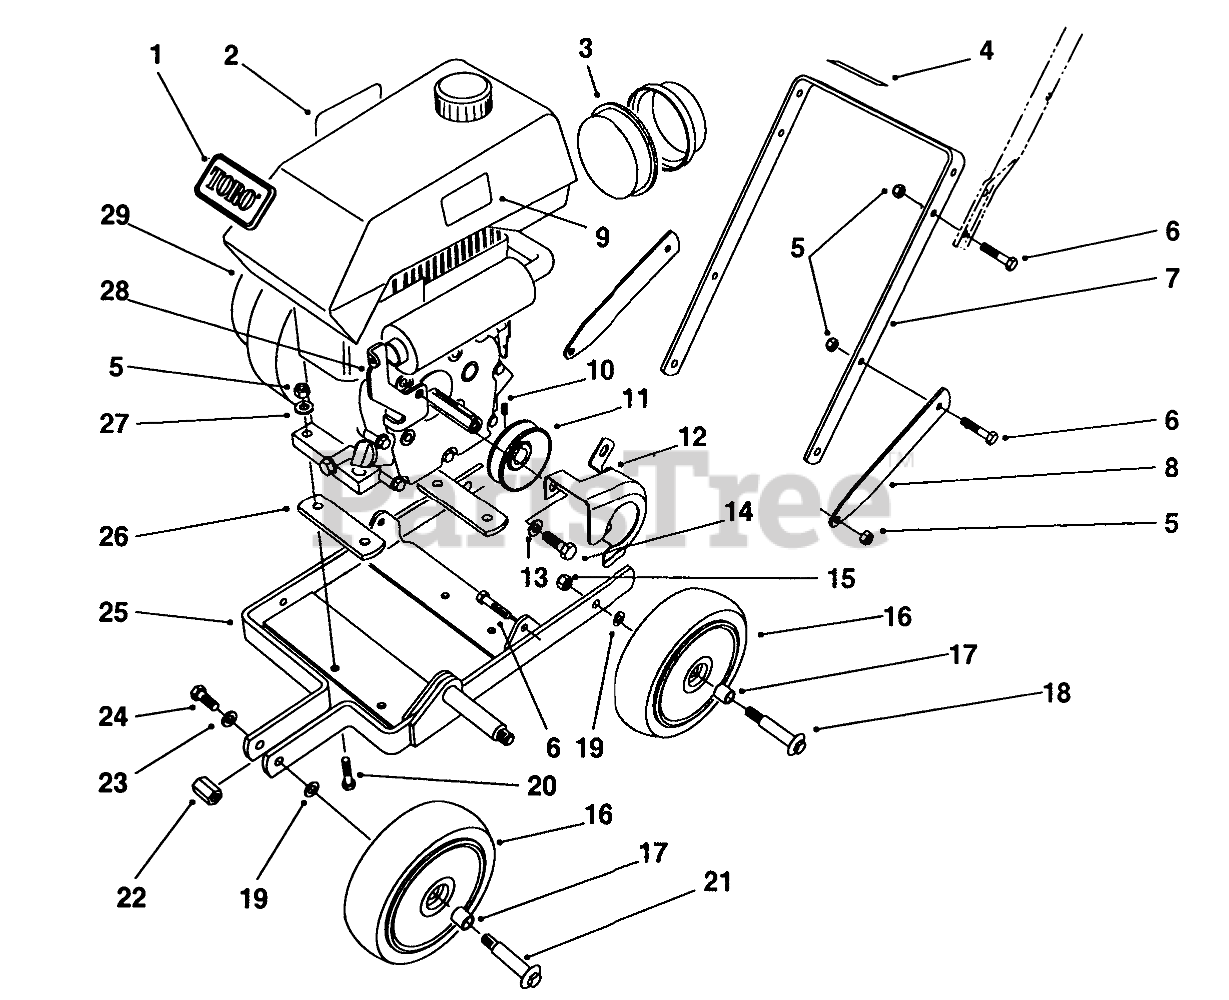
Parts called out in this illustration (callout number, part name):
1	TORO LOGO PLT
2	OPERATING INST DECAL
3	FILTER FOAM
4	Decal-Warning
5	NUT-LOCK, NI
6	SCREW-HH
7	LOWER HANDLE
8	SUPPORT HANDLE
9	Decal-Hot
10	SCREW-SET
11	2HP PULLEY
12	ENG. PULLEY GUARD
13	WASHER-LOCK
14	SCREW-HH
15	NUT-HEX
16	Wheel & Tire Assembly (Incl. Ref. #17)
17	BUSHING
18	WHEEL BOLT
19	WASHER
20	SCREW-HH
21	BOLT-WHEEL
22	HEX SPACER
23	WASHER-LOCK
24	SCREW-HH
25	Frame-Edger
26	Pats-Spacer
27	WASHER-PLAIN
28	SPRING BRKT R
29	Engine (Complete)
